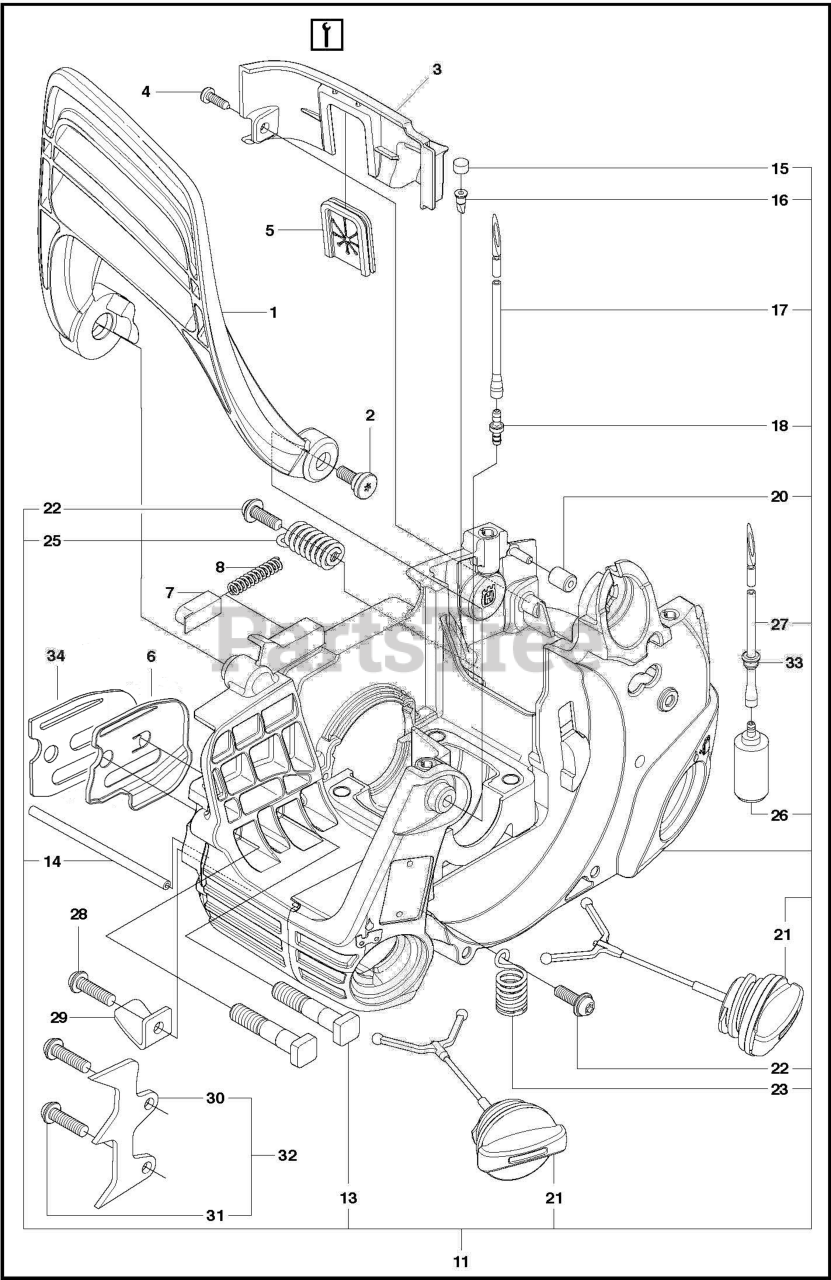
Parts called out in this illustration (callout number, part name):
1	HANDGUARD HHS
2	BOSS SCREW
3	REAR WALL
4	SCREW 6-19X.437
5	GROMMET
6	PLATE BAR
7	CAP, SPRING HANDGUARD
8	SPRING
11	Chassis
11	CHASSIS ASSEMBLY, P021, MACH.
13	BOLT
14	OIL TUBE
15	VENT,FUEL TANK 36/41
16	VALVE-CHECK (DUCKBILL)
17	KIT FUEL LINE
18	FUEL LINE FITTING
20	ISOLATOR FILTER HOUSING
21	ASSY TANK CAP GREY
22	SCREW,FRONT HBAR 36/41
23	ISOLATOR
25	SPRING
25	SPRING REAR HANDLE ISOLATOR 96
26	ASSY FUEL PICKUP PRE FLUSHED
27	KIT FUEL LINE
28	SCREW
29	CHAIN CATCHER 36/41
30	SPIKE
31	SCREW
32	SPIKE 36/41
33	FUEL TANK BUSHING
33	GROMMET FUEL LINE
34	Spacers
